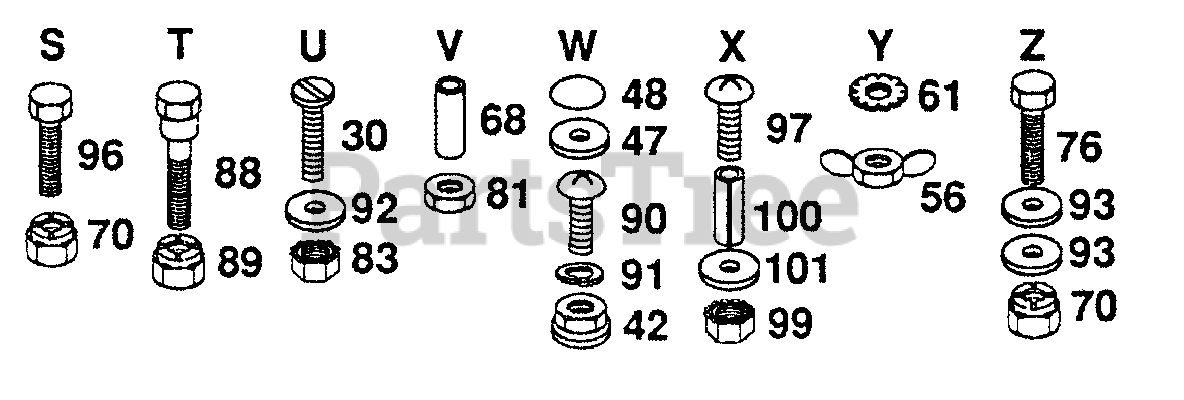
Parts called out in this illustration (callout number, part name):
30	Screw, Mach. Cr. Threaded 5/16-18x3/4
42	Nut, Weld
47	Washer, Cap, Snap
56	Nut, Wing
61	Washer, Lock, Int/Ext Tooth 1/4
70	Nut, Crownlock 3/8 - 16
76	Bolt, Hex 3/8 - 16 x 1
81	Nut, Fin, Hex 1/4 - 20 UNC
83	Nut, Keps 5/16 - 18
88	Bolt, Shoulder 1/4 - 20
89	Nut, Crownlock 1/4 - 20
90	Screw, Pan, Mach. #10 - 24 x 1/2
91	Washer, Lock #10
92	Washer 11/32 x 11/16 x 16 Gauge
93	Washer 13/32 x 13/16 x 12 Gauge
96	Bolt, Hex 3/8 - 16 x 3/4
97	Screw, Mach. Cr. Pan #10-24x 1-1/4
99	Nut, Keps 10 - 24
100	Spacer, Split 10 x 3/4
101	Washer 7/32 x 1/2 x 18 Gauge
